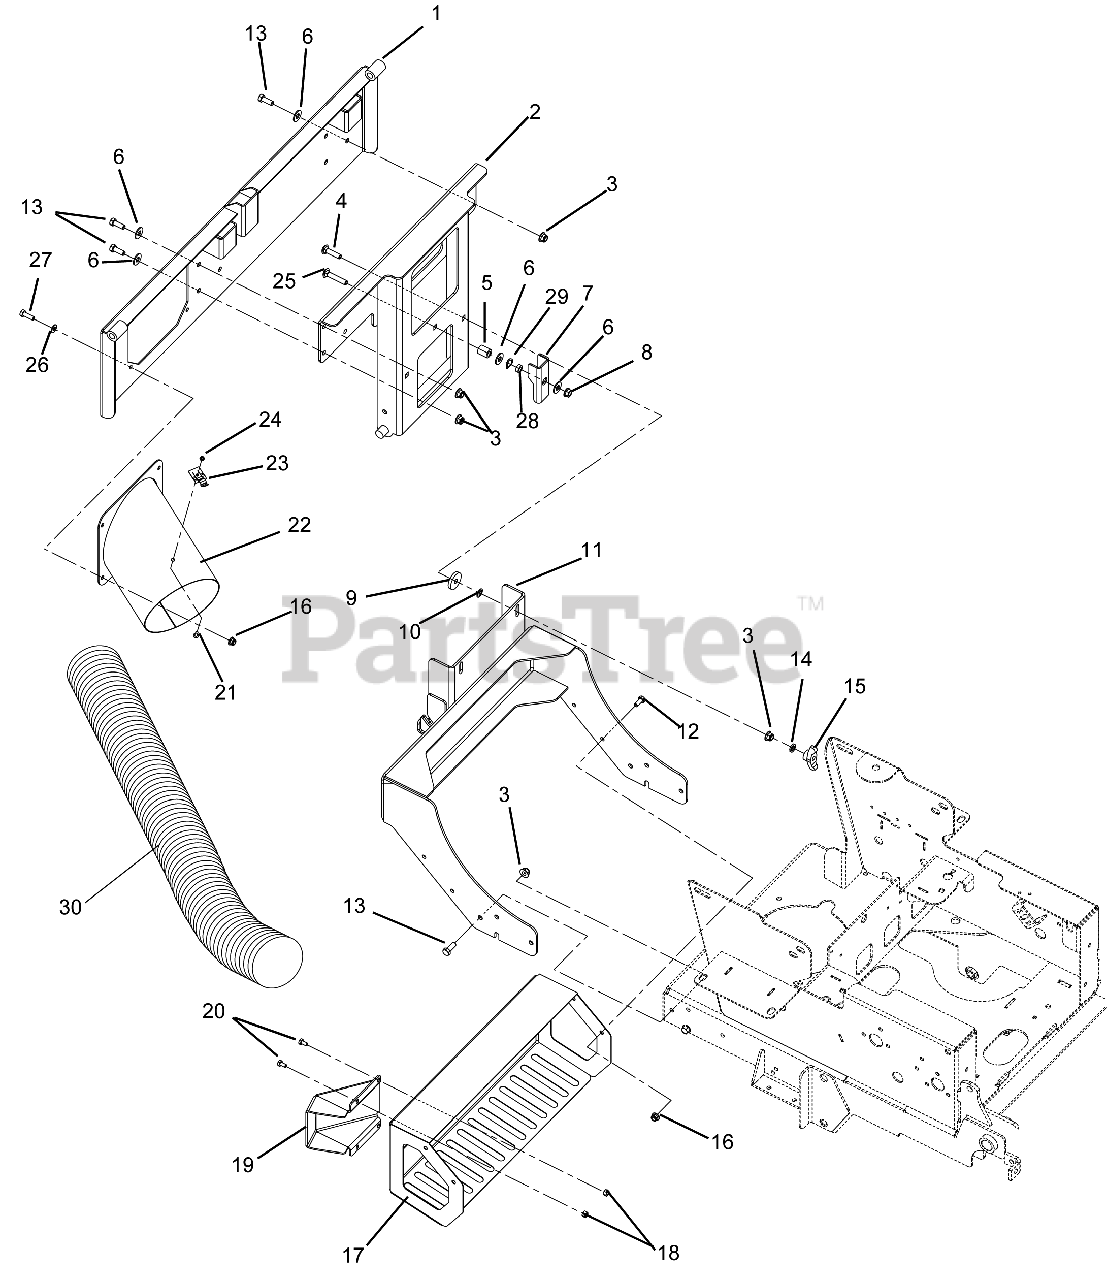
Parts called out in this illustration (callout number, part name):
1	RCPTCL,HUMBOLDT 2-BAG W/O GRAV
2	WMT-UPPER MOUNT - 2 BAG
3	@NUT-LK-NYL-FLG .38-16 YWZC
4	@BLT-RDHDSQNK .38-16X1.75 G5YZ
5	BSHG,SPCR .41 X .75 X .88 PM
6	@WSHR-FL-STL.438X1.00X.083 YWZ
7	LATCH - BAGGER UPPER MOUNT
8	@NUT-LK-TOP-FLG .38-16 YWZC
9	WSHR,FLT STL.406X1.50X.245YWZC
10	NUT-PUSH .38 DIA. PAL ZINC
11	WMT - LOWER MOUNT - 2 BAG
12	@BLT-HEX .31-18X.75 GR5 YWZC
13	@BLT-HEX .38-16X1.00 GR5 YWZC
14	WSHR-LK .375X.115 HVY YWZC
15	NUT-WING .38-16
16	@NUT-LK-NYL-FLG .31-18 YWZC
17	SHIELD - HEAT
18	@NUT-LK-CTR .25-20 YWZC
19	DEFLECTOR - EXHAUST - MZ
20	@BLT-HEX .25-20X.50 GR5 YWZC
21	@SCR-MCH 10-24X.50 HWH YWZC
22	INLET ADAPTER 100 SERIES
23	THUMB LATCH
24	@NUT-LK-NYL 10-24 W/INSRT YWZC
25	@BLT-RDHDSQNK .38-16X2.00 G5YZ
26	@WSHR-FL-STL.344X.688X.065YWZC
27	@BLT-HEX .31-18X1.00 GR5 YWZC
28	BSHG-SLV .377X.624X.235
29	WAVE WASHER .640X.875X.125FH
30	HOSE,7X63 GOODYEAR 586-429-171
